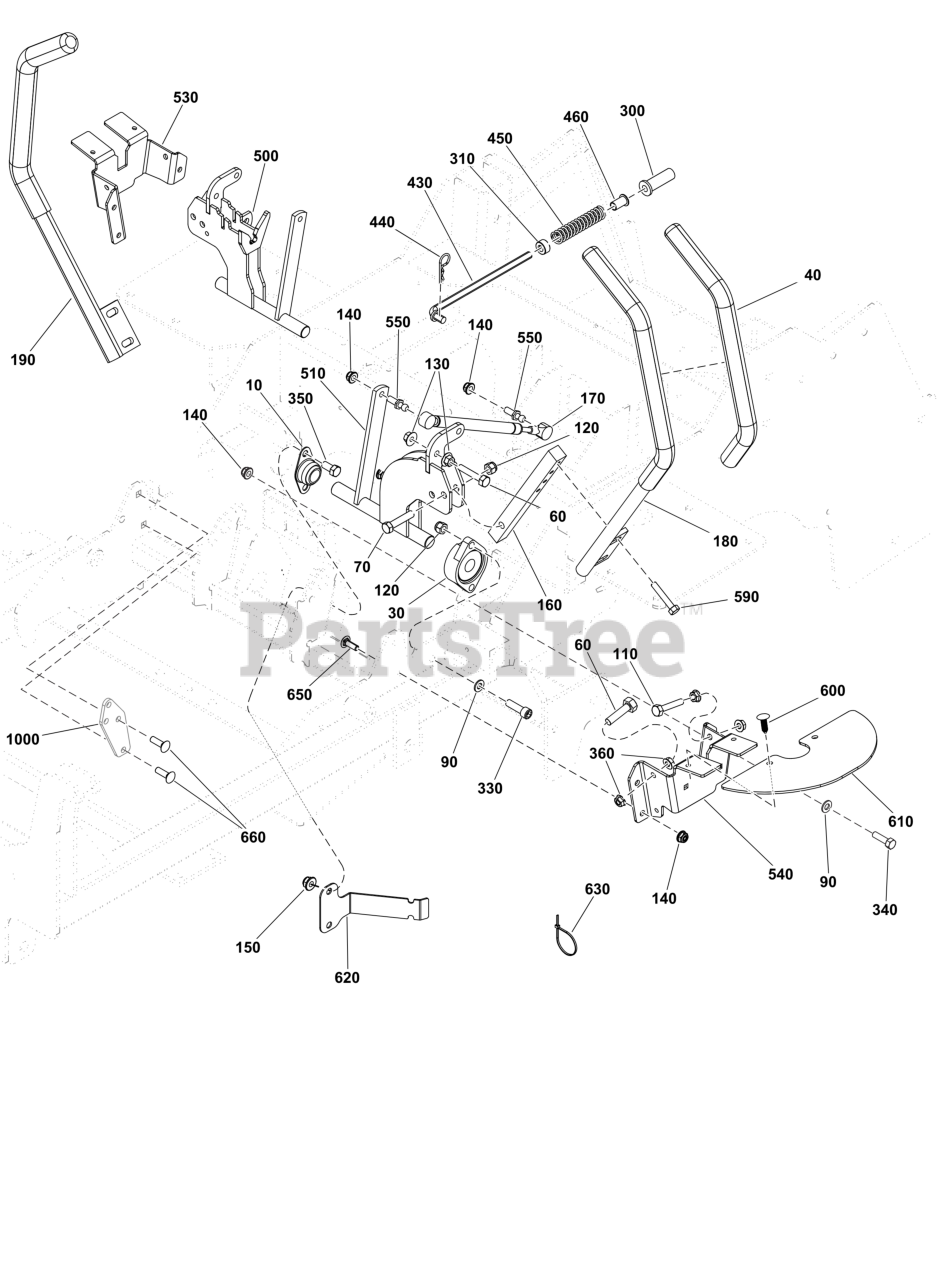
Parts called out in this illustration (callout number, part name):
10	BEARING, BRONZE FLANG
30	BEARING, FLANGE
40	GRIP
60	BOLT, 5/16-18 X 1-1/4
70	BOLT, 3/8-16 X 1-3/4"
90	WASHER
110	BOLT, 5/16-18 X 1-3/4
120	NUT, 3/8-16 HEX NYLON
130	NUT, 5/16-18 HEX SERR
140	NUT
150	NUT, 3/8-16 HEX NYLOCK
160	MOUNT, CONTROL ARM
170	DAMPNER, CONTROL
180	CONTROL, HANDLE
190	CONTROL, HANDLE
300	BUSHING, FLANGED, 3/8
310	COLLAR, 3/8" SET
330	BOLT, 3/8-16 X 1-1/4
340	BOLT, 5/16-18 X 3/4"
350	BOLT, 3/8-16 X 3/4" G
360	NUT, 5/16-18 HEX SERR
430	ROD, NEUTRAL
440	PIN, HAIR, .0915 X 1-7/8
450	SPRING, REVERSE RETUR
460	BUSHING, NYLON
500	SHAFT-CONTROL
510	SHAFT-CONTROL
550	10MM BALL STUD, 5/16-
590	SCREW, 5/16-18
600	PUSH RIVET (TREE TYPE
610	GUARD, RUBBER MOTION
620	BRACKET, HARNESS MOUNT, 2100 - BLK
630	TIE WRAP, 5-1/2" LONG
650	BOLT, 5/16-18 X 3/4",
660	BOLT, 5/16-18 X 1", C
1000	Refer to: Parking Brake Group
